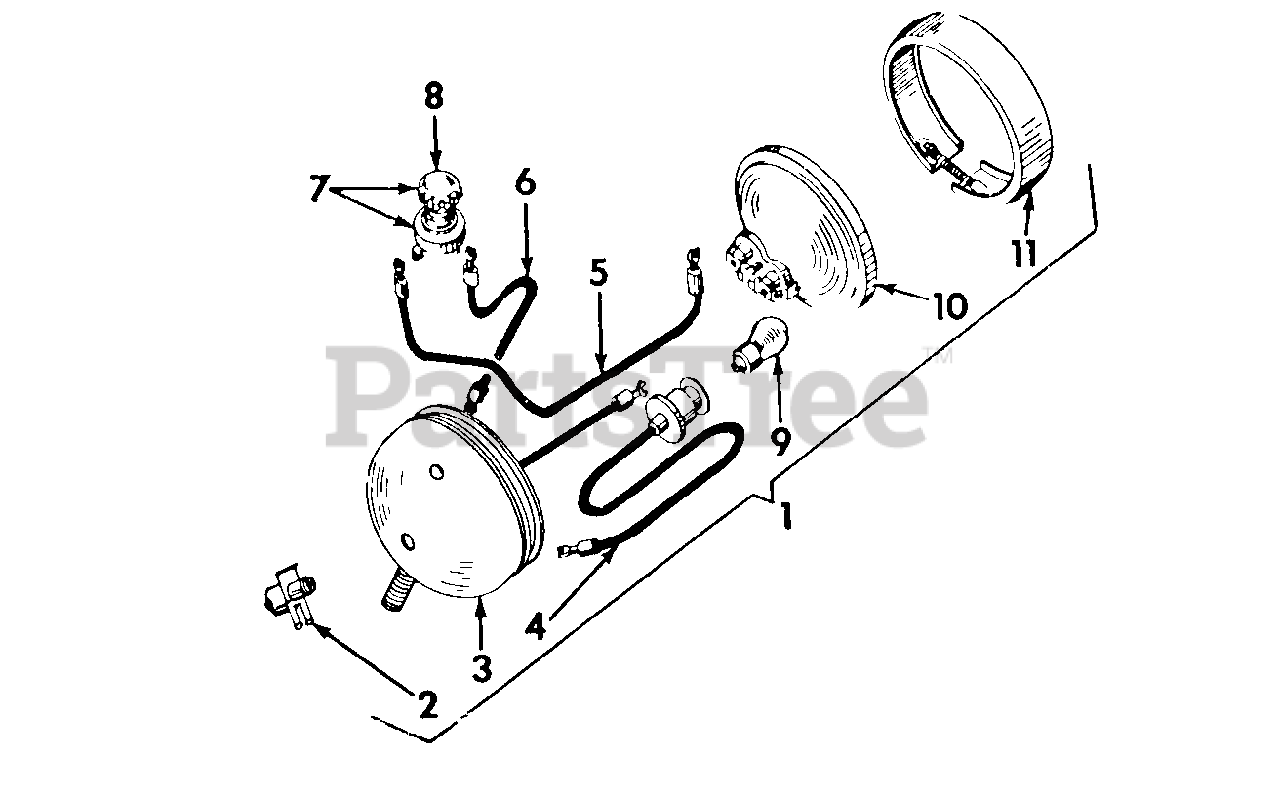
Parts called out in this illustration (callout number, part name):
1	LIGHT ASSY COMBINATION REAR AND TAIL - 6 VOLT
2	PACKAGE, TERMINAL PLATE ASSY
3	BODY, LIGHT
4	SOCKET AND WIRE, SWITCH TO RED LIGHT
5	WIRE, SWITCH TO SEALED BEAM UNIT
6	WIRE, SWITCH TO CONNECTOR
7	SWITCH ASSY, LIGHT
8	KNOB LIGHT SWITCH
9	LAMP NO 209 - 6 VOLT
10	UNIT, SEALED BEAM
11	MOULDING ASSY.
